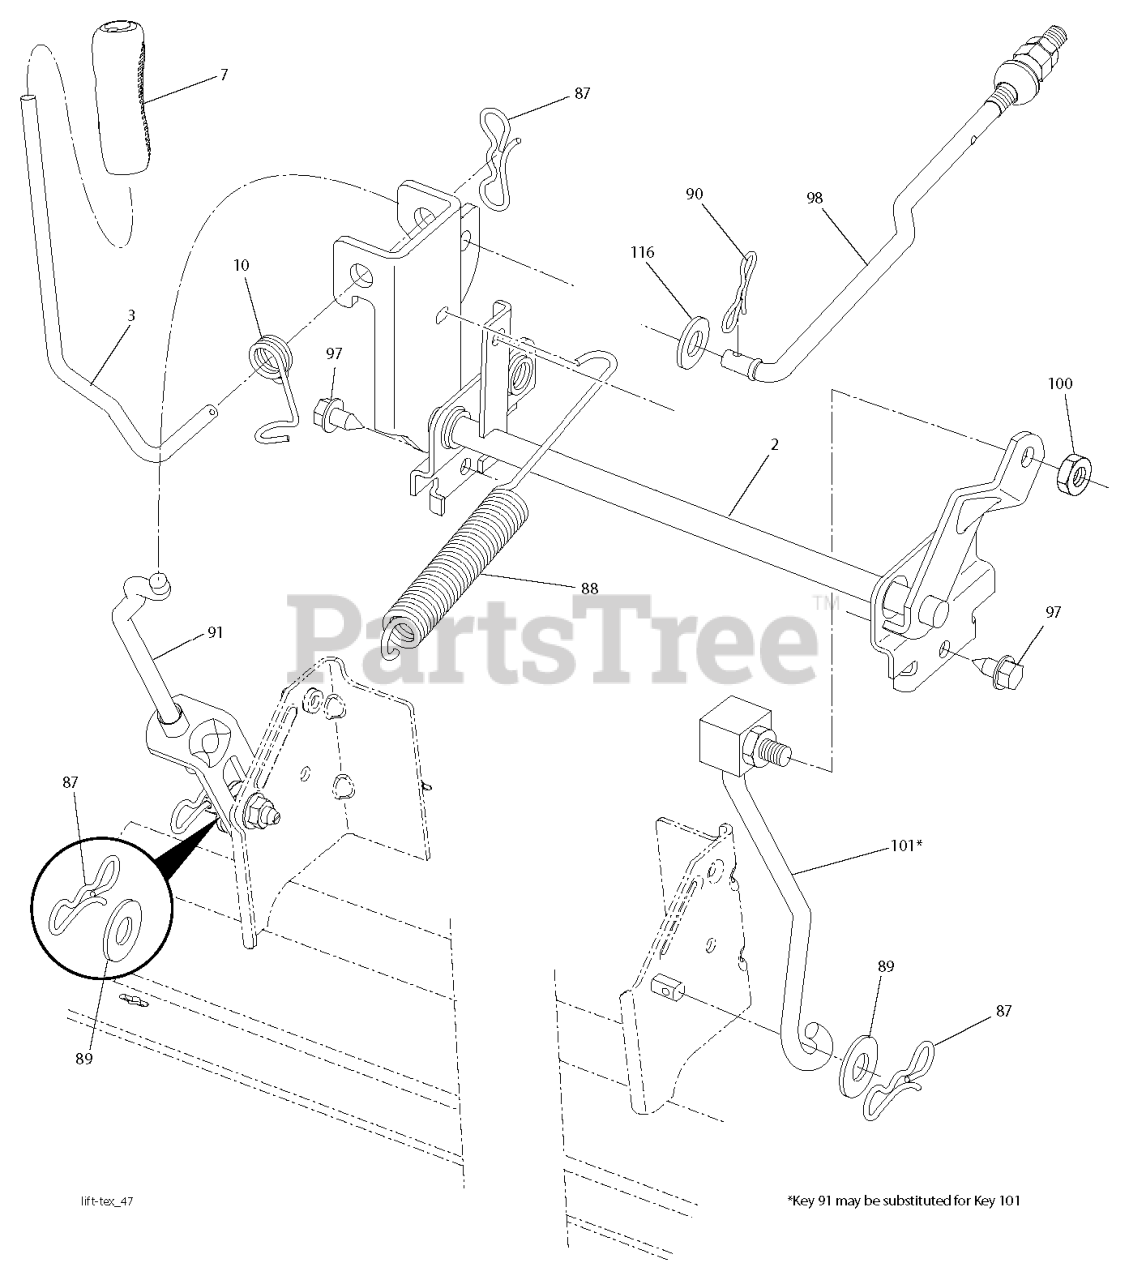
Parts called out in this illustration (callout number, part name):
2	SHAFT.ASM.CROSS.LIFT
7	GRIP.HANDLE.LIFT.PVC.BLACK
10	SPRING.TORSION.LIFT.HANDLE
87	PIN.COTTER.7/16.BOW TI.
88	SPRING.LIFT.ASSIST
89	WASHER.CLEAR.ZINC
90	PIN.COTTER.5/16.BOW TI
91	LINK ASSY LIFT.REAR 10.278
97	SCREW, 3/8-16X3/4
101	LINK.ASM.LIFT.FIXE.38/42/46"
